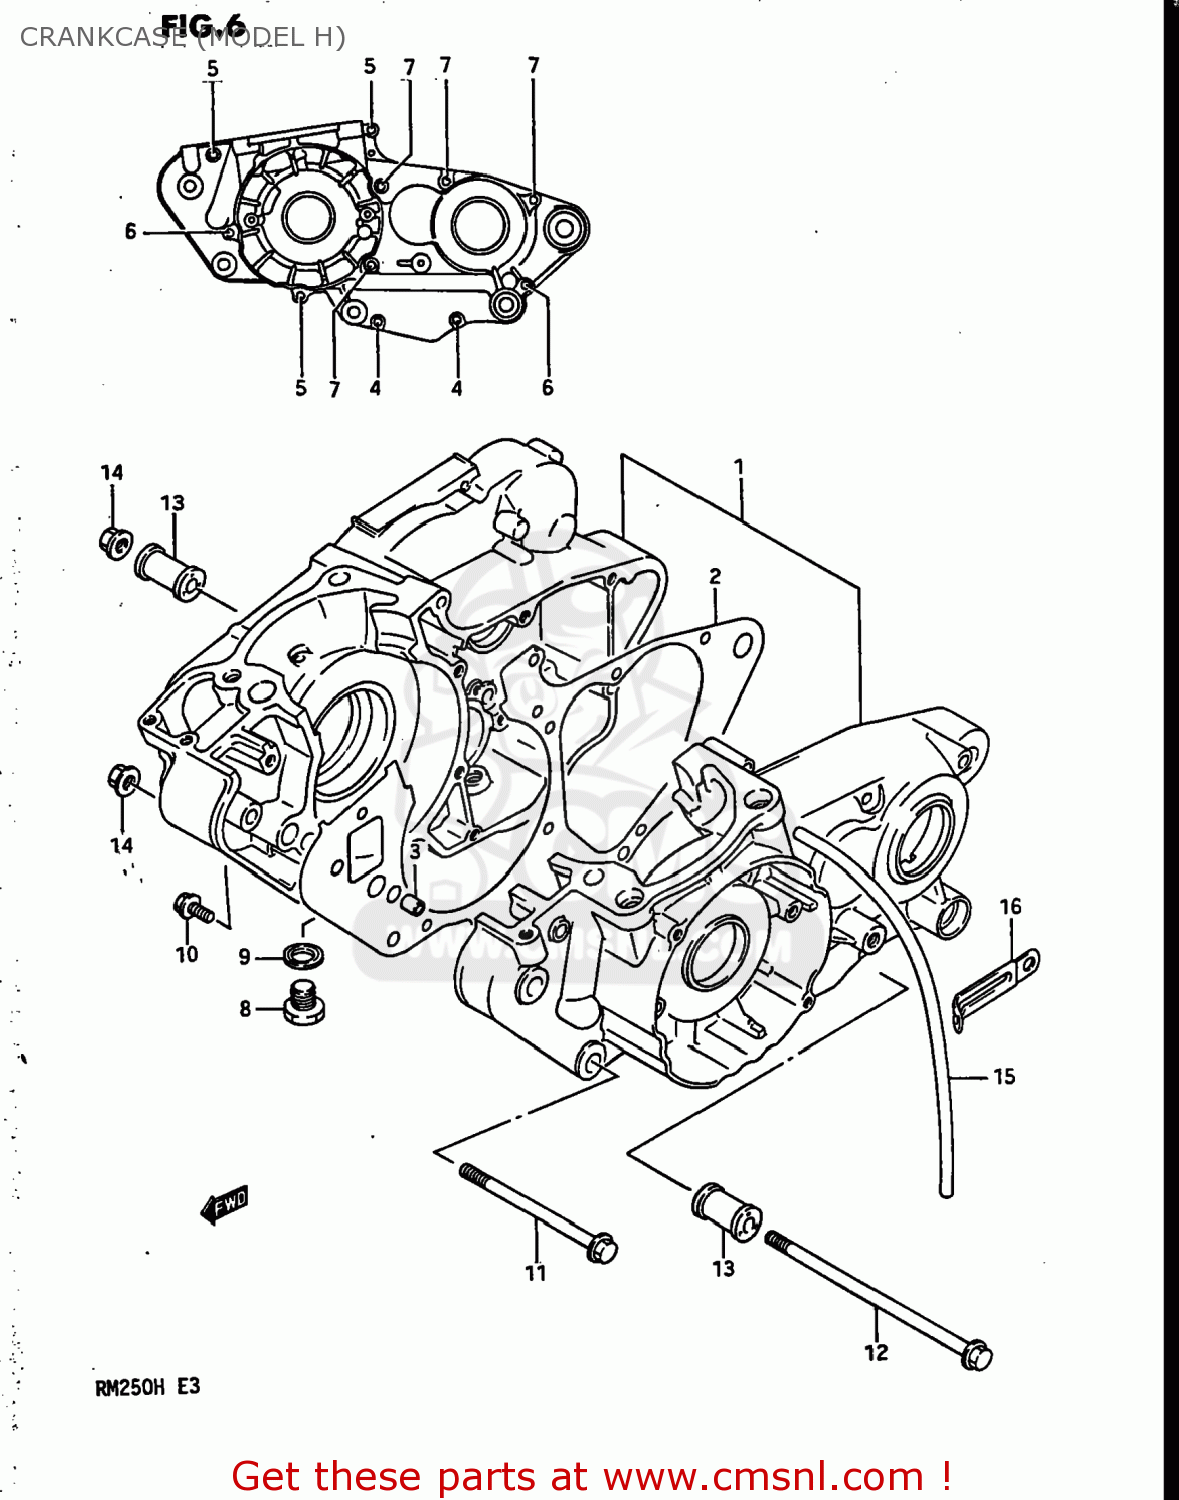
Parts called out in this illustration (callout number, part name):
1	CRANKCASE SET
2	GASKET,CRANKCASE (MCA)
3	PIN
4	SCREW
5	SCREW
6	SCREW
7	SCREW 6X60
8	PLUG
9	GASKET(14X19.2X2) (NAS)
10	SCREW (6X10)
11	BOLT(8X100)
12	BOLT
13	SPACER,ENGINE MOUNT(L:32)
14	NUT
15	HOSE
16	CLAMP
